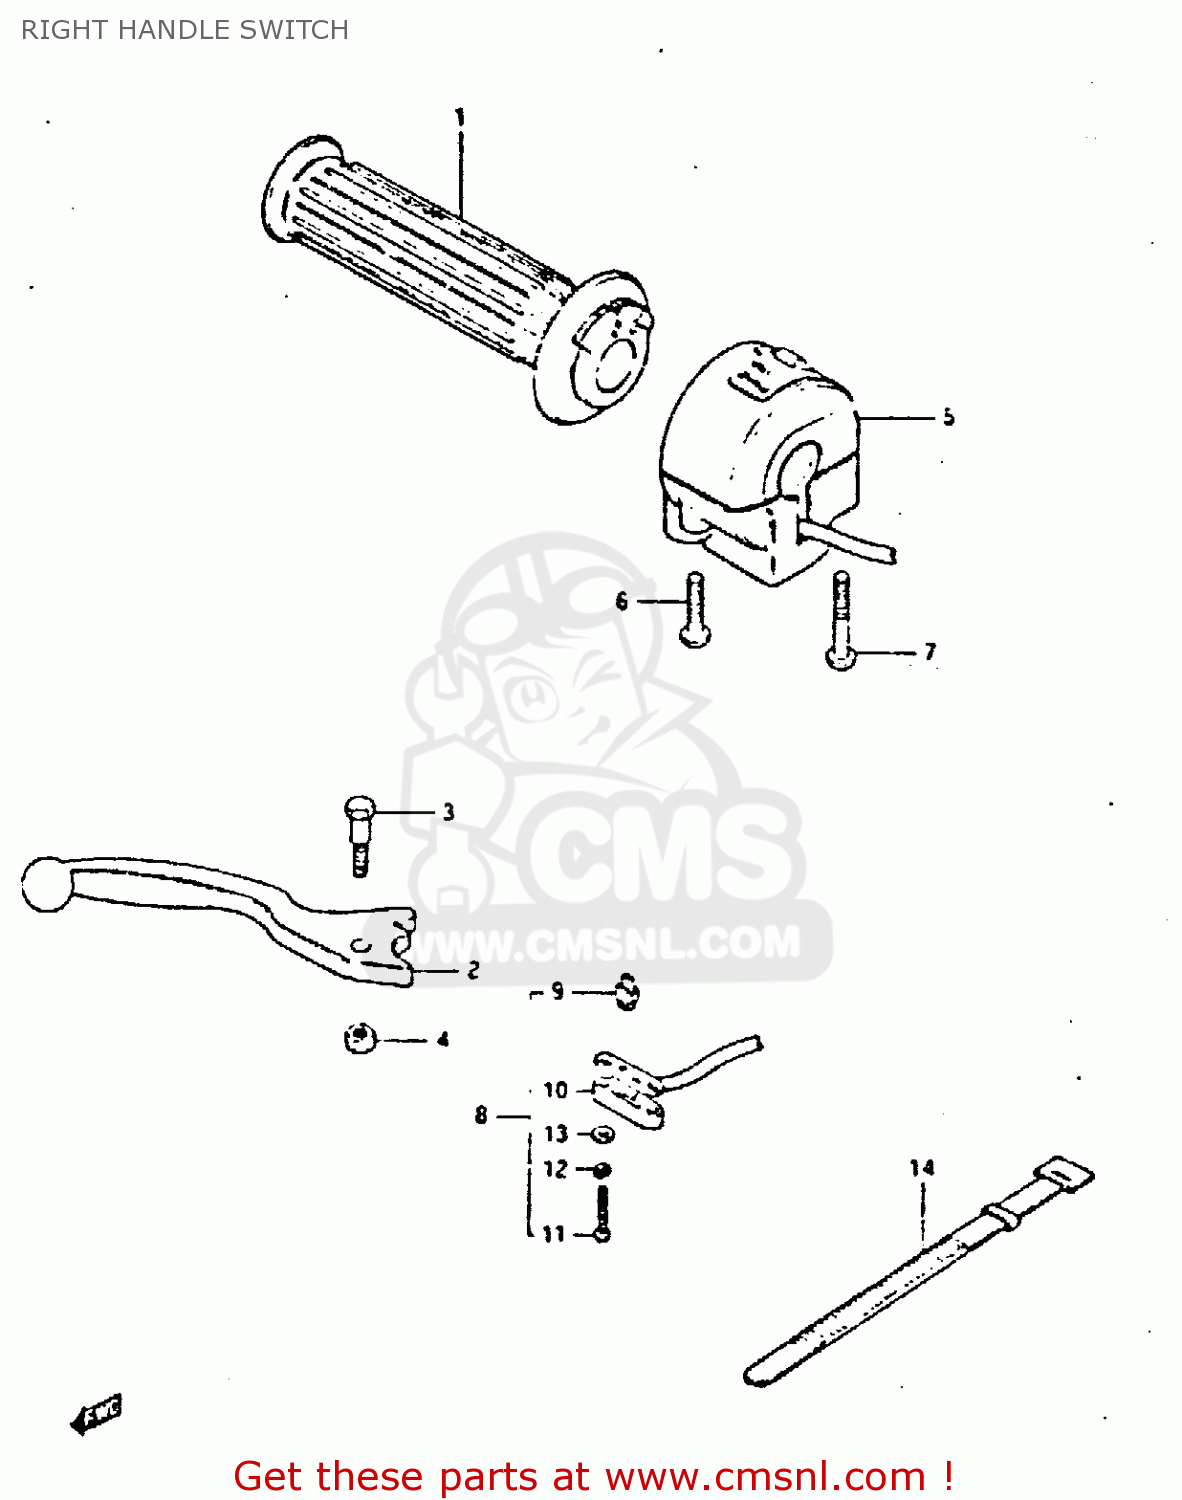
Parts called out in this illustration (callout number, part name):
1	GRIP,THROTTLE
2	LEVER,BRAKE
3	BOLT
4	NUT 6MM
5	SWITCH ASSEMBLY,HANDLE,RIGHT
6	SCREW
7	SCREW
14	CLAMP(L:120)
